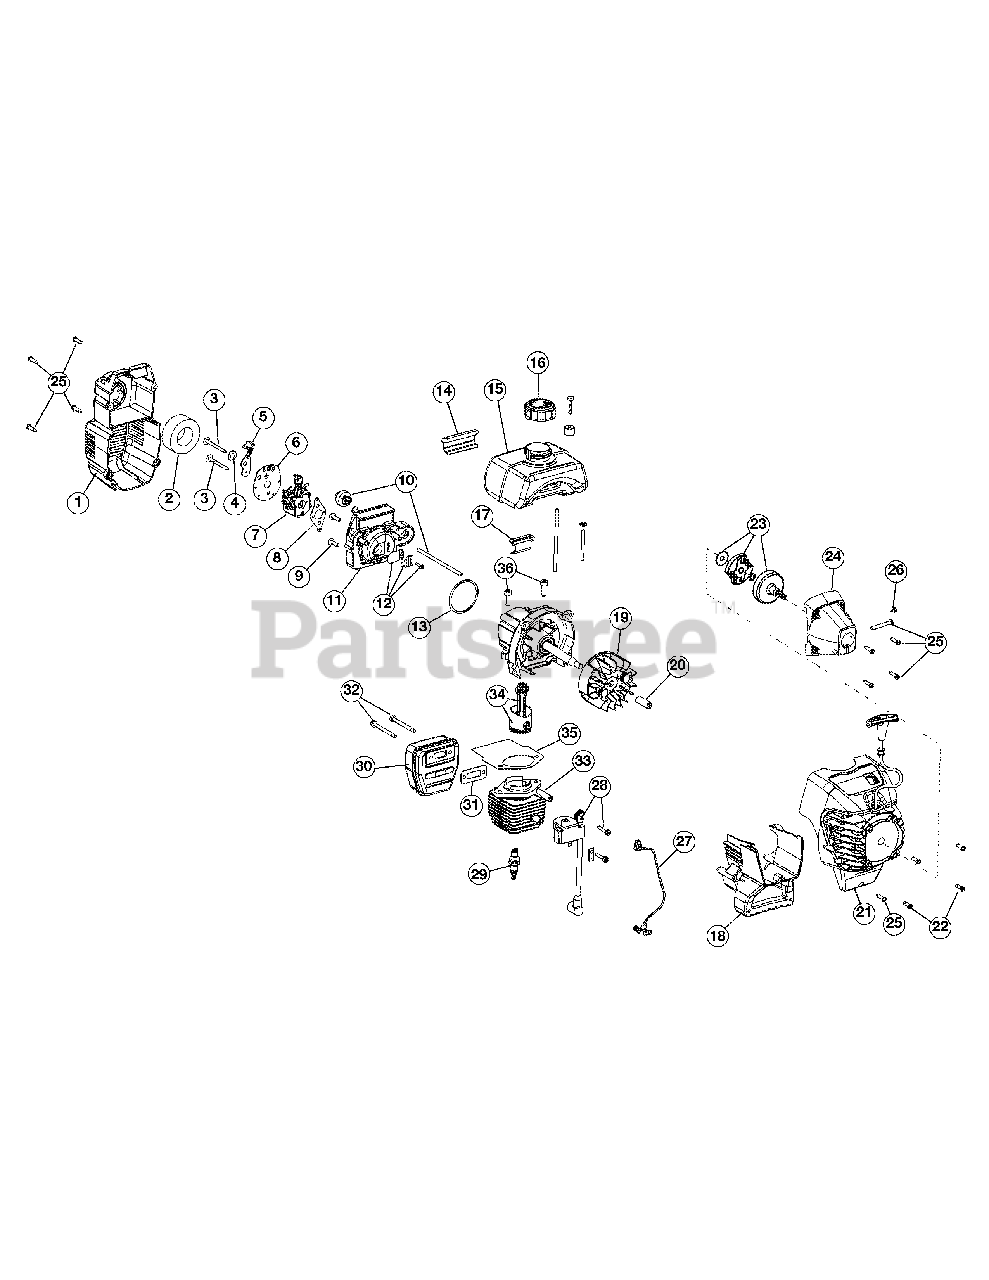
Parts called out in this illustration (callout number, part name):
1	Air Cleaner Cover Assembly
2	Air Cleaner Filter
3	Carburetor Mounting Screw Assembly
4	Wavey Washer
5	Choke Lever
6	Choke Plate
7	Carburetor Assembly
7	Carburetor Kit - Walbro
7	Carburetor Kit - Zama
7	Carburetor Kit - Ruixing
8	Carburetor Gasket
9	Carb Mount Screw
10	Primer & Hose Assembly
11	Carb Mount Assembly
12	Reed Assembly
13	Carburetor O-Ring
14	Rear Mounting Pad
15	Fuel Tank Assembly
16	Fuel Cap Assembly
17	Front Mounting Pad
18	Shroud Extension & Stand
19	Flywheel Assembly
21	Starter Housing Assembly
22	Housing Screw
23	Clutch Rotor Assembly
24	Clutch Cover Assembly
25	Cover Screw
26	Anti-Rotation Screw
27	Wire Leads and Sleeve
28	Module Assembly
30	Muffler Assembly
31	Exhaust Gasket
32	Muffler Mounting Bolts
33	Cylinder Assembly
34	Piston and Rod Assembly
35	Cylinder Gasket
36	Cylinder Bolt
